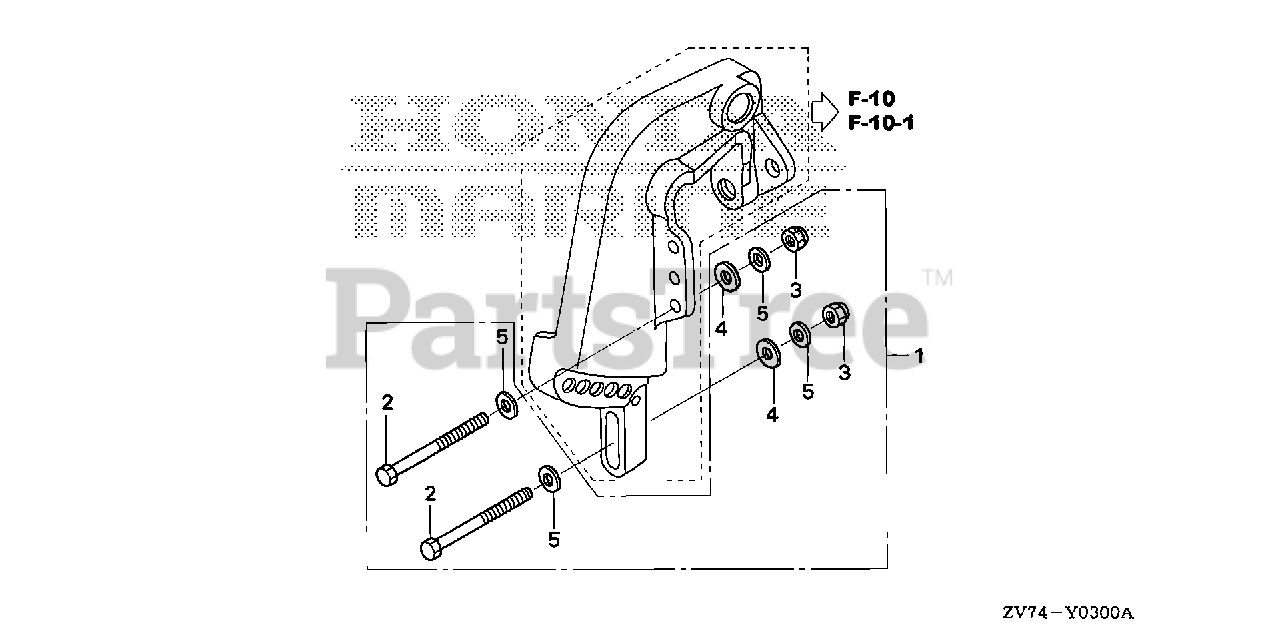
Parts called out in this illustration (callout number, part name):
1	INSTALLATION KIT, OUTBOARD
2	BOLT, HEX. (10X100)
3	NUT, SELF-LOCK (10MM)
4	WASHER, PLAIN (10MM)
5	WASHER, PLAIN (10MM)
